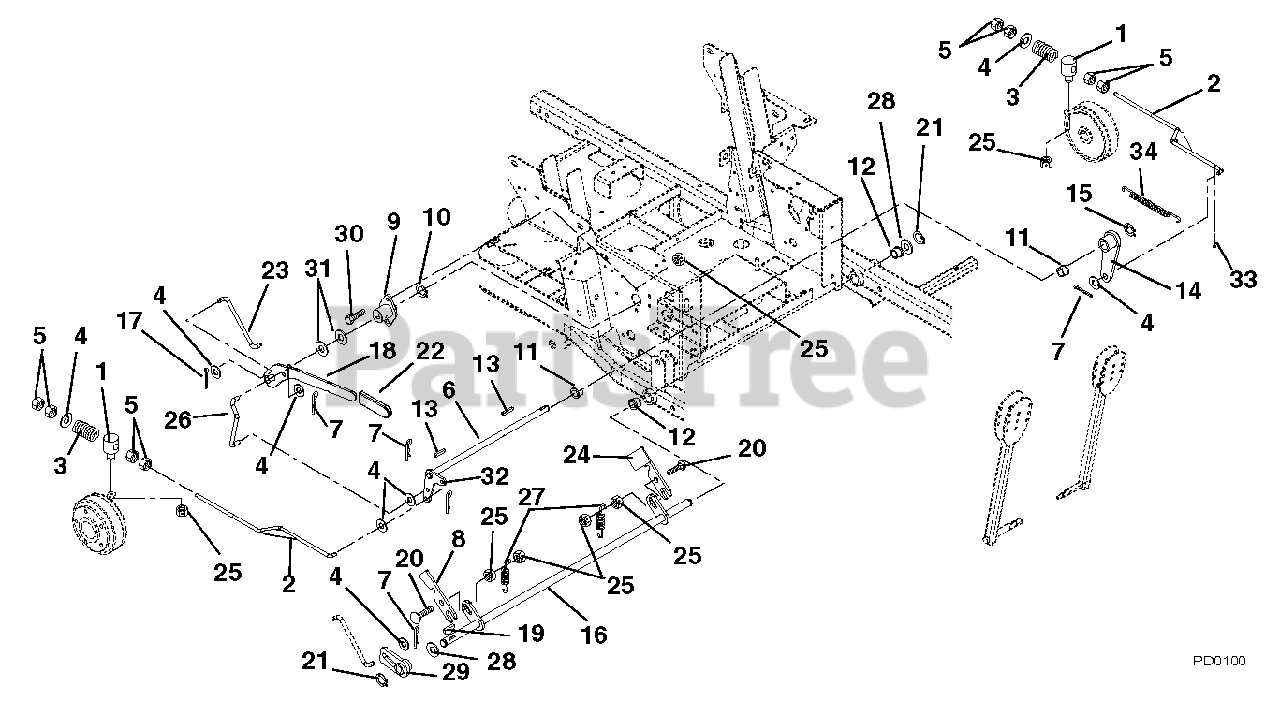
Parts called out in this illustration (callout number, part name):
1	Pivot, Brake Rod
2	Rod, Brake 200 XDZ LPG
3	Spring, Compression .142 x .710 x 1.75
4	Washer, Flat Steel .406 x .812 x .065
5	Nut, Hex .38-16
6	Shaft, Brake Cross
7	Pin, Hair
8	Slide, Interlocking Brake
9	Bushing, Flange
10	Ring, Retaining External .625 x .05
11	Bushing, Flange Nylon .762 x 1.00 x .58 x 1.48
12	Bushing, Flange .515 x .75 x .745 x 1.00
13	Key, Square .188 x 1.00 x .188
14	Arm, Brake Left Hand
15	Ring, Retaining External .689 x .078
16	Weldment, Mechanical Brake
17	Pin, Cotter External .09 x .75
18	Weldment, Brake Actuating
19	Key, Woodruff .13 x .63
20	Bolt, Round Head Square Neck .31-18 x 1.25 Grade 5
21	Ring, Retaining External .50 x .05
22	Grip, Handle
23	Linkage, Brake Actuating
24	Interlock, Safety Switch
25	Nut, Locking Top Flange .31-18
26	Linkage, Brake Actuating
27	Spring, Tension .063 x .44 x 1.56
28	Washer, Flat Steel .505 x 1.00 x .062
29	Weldment, Parking Brake Hub
30	Bolt, Hex .31-18 x .75 Grade 5
31	Washer, Flat Steel .630 x 1.250 x .062
32	Weldment, 200 Brake Actuating Arm
33	Pin, Cotter .12 x .75 Extended Prong Square Cut
34	Spring, Extension
